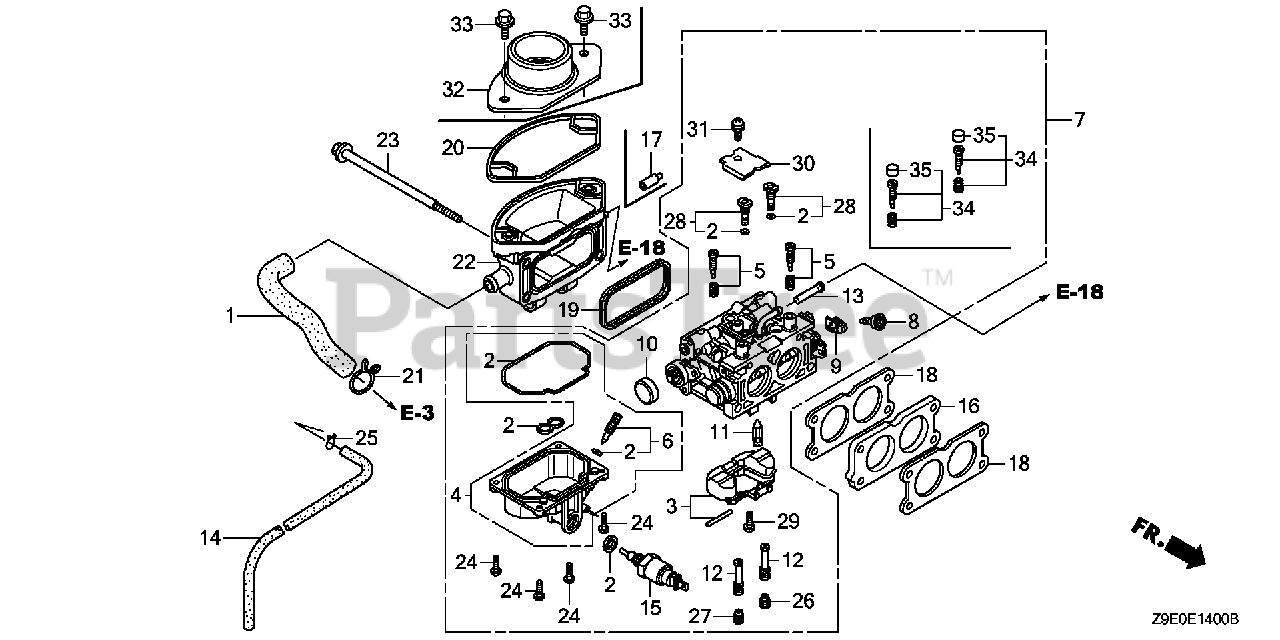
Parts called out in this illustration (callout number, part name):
1	TUBE, BREATHER
2	GASKET SET
4	CHAMBER SET, FLOAT
5	SCREW SET (CARBURETOR NO.)
6	SCREW SET, DRAIN (ADVENTURE GREEN) (CARBURETOR NO.)
7	CARBURETOR ASSY. (BK07A D)
8	SCREW, THROTTLE STOP
9	ARM, THROTTLE LINKAGE
10	CAP, CHOKE LEVER DUST
11	VALVE, FLOAT
12	NOZZLE, MAIN (CARBURETOR NO.)
13	SCREEN, FUEL STRAINER
14	TUBE, DRAIN
15	VALVE ASSY., SOLENOID
16	INSULATOR, CARBURETOR
18	GASKET, CARBURETOR
19	GASKET, AIR CLEANER
20	SEAL, AIR CLEANER HOUSING
21	CLIP, BREATHER TUBE
22	ELBOW, AIR CLEANER
23	BOLT, FLANGE (6X106)
24	SCREW, PAN (4X12)
25	CLIP, TUBE (B8)
26	JET, MAIN (#90) Use from Engine SN BE81B C.
26	JET, MAIN (#95)
26	JET, MAIN (#98) Use from Engine SN BE87A A to BE87A A.
26	JET, MAIN (#102) (ADVENTURE GREEN) (CARBURETOR NO.)
26	JET, MAIN (#110) (CARBURETOR NO.)
27	JET, MAIN (#92)
27	JET, MAIN (#98) Use from Engine SN BE87A A to BE87A A.
27	JET, MAIN (#102) (ADVENTURE GREEN) (CARBURETOR NO.)
27	JET, MAIN (#105) Use from Engine SN BE87H A.
27	JET, MAIN (#110) (CARBURETOR NO.)
28	JET SET, PILOT (#40) (ADVENTURE GREEN) (CARBURETOR NO.)
29	SCREW, FLOAT
31	SCREW-WASHER (5X10)
34	SCREW SET (CARBURETOR NO.)
35	CAP, ADJUSTING SCREW (CARBURETOR NO.)
